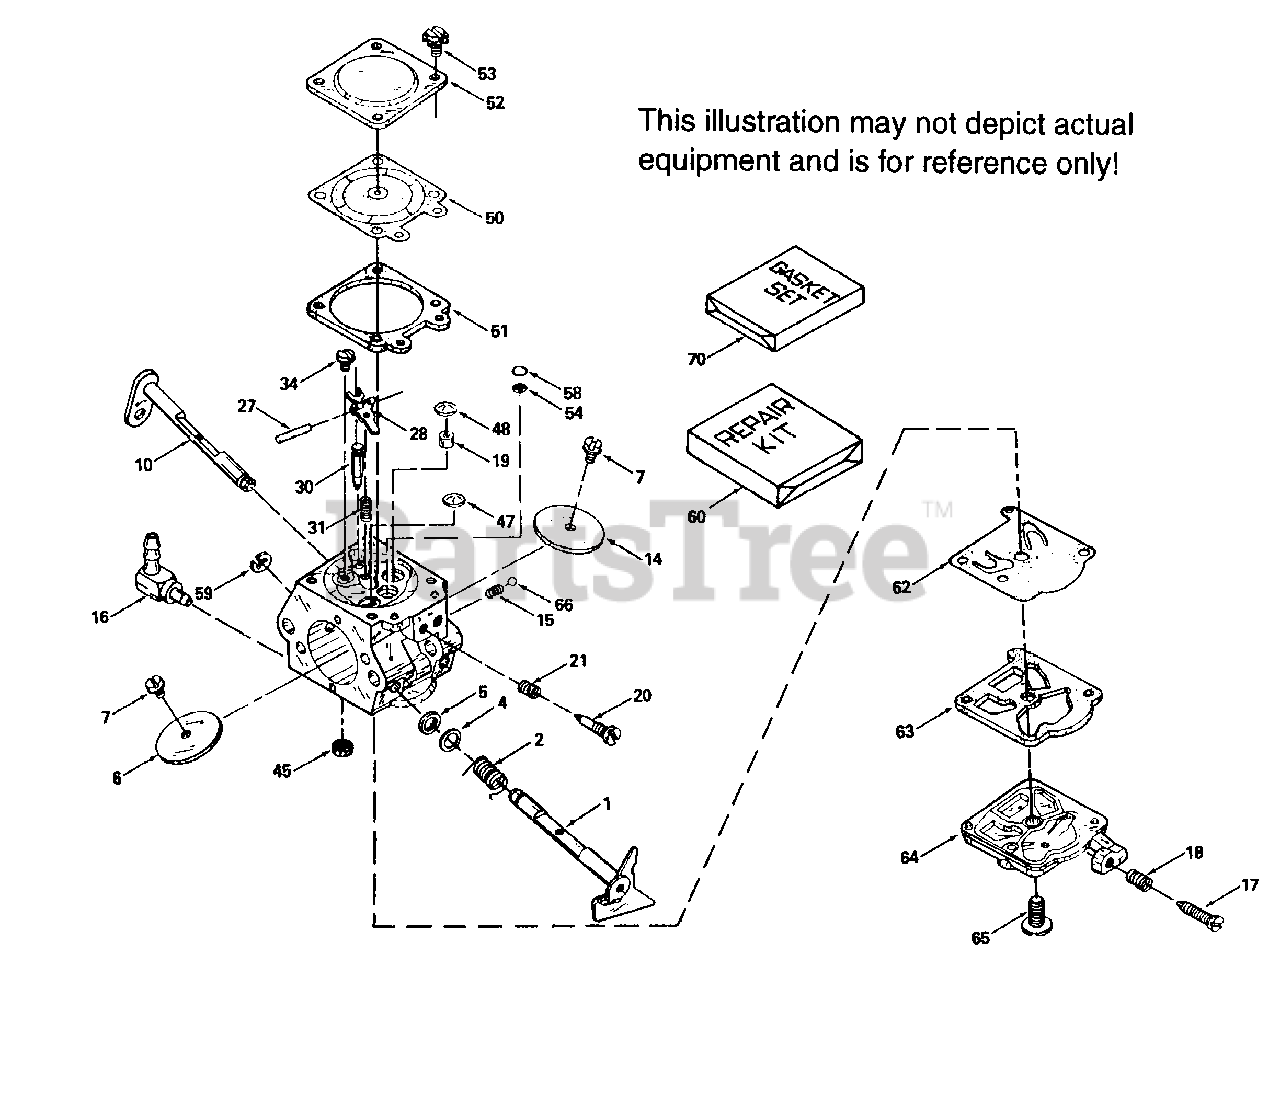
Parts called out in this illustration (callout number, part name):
1	Throttle Shaft & Lever Ass'y.
2	* Throttle Return Spring
4	Dust Seal Washer
5	Dust Seal (Throttle)
6	Throttle Shutter
7	* Throttle & Choke Shutter Screw
10	Choke Shaft & Lever Ass'y.
14	Choke Shutter
15	* Choke Positioning Spring
16	Fuel Fitting
17	Idle Speed Screw
18	Tension Spring
19	Check Valve Nozzle (Incl. 48)
20	* Idle Mixture Screw
21	Idle Tension Spring
27	* Hinge Pin
28	* Metering Lever
30	* Inlet Needle
31	* Metering Lever Spring
34	* Metering Lever Pin Screw
45	* Fuel Inlet Screen
47	* Welch Plug
48	* Welch Plug
50	* Diaphragm (Included in 60 & 70)
51	* Cover Gasket (Included in 60 & 70)
53	Cover Screw
54	* Check Valve Screen
58	* Screen Retaining Ring
60	Repair Kit (Incl. items marked PK in notes) Incl. 1 each of 632287, 63229 5, 632297, 632298, 632299, 632300A, 6 32301, 632303, 632304, 632307, 632311 , 632312, 632314, 632315A, 632316, 63 2318, 632320A, 632374, 632476, 2 of 6 50506
62	* Pump Diaphragm (Included in 60 & 70)
63	* Pump Gasket (Included in 60 & 70)
64	Pump Cover
65	Pump Cover Screw
66	* Choke Friction Ball
70	* Diaphragm/Gasket Set Incl. 50, 51, 6 2 & 63
